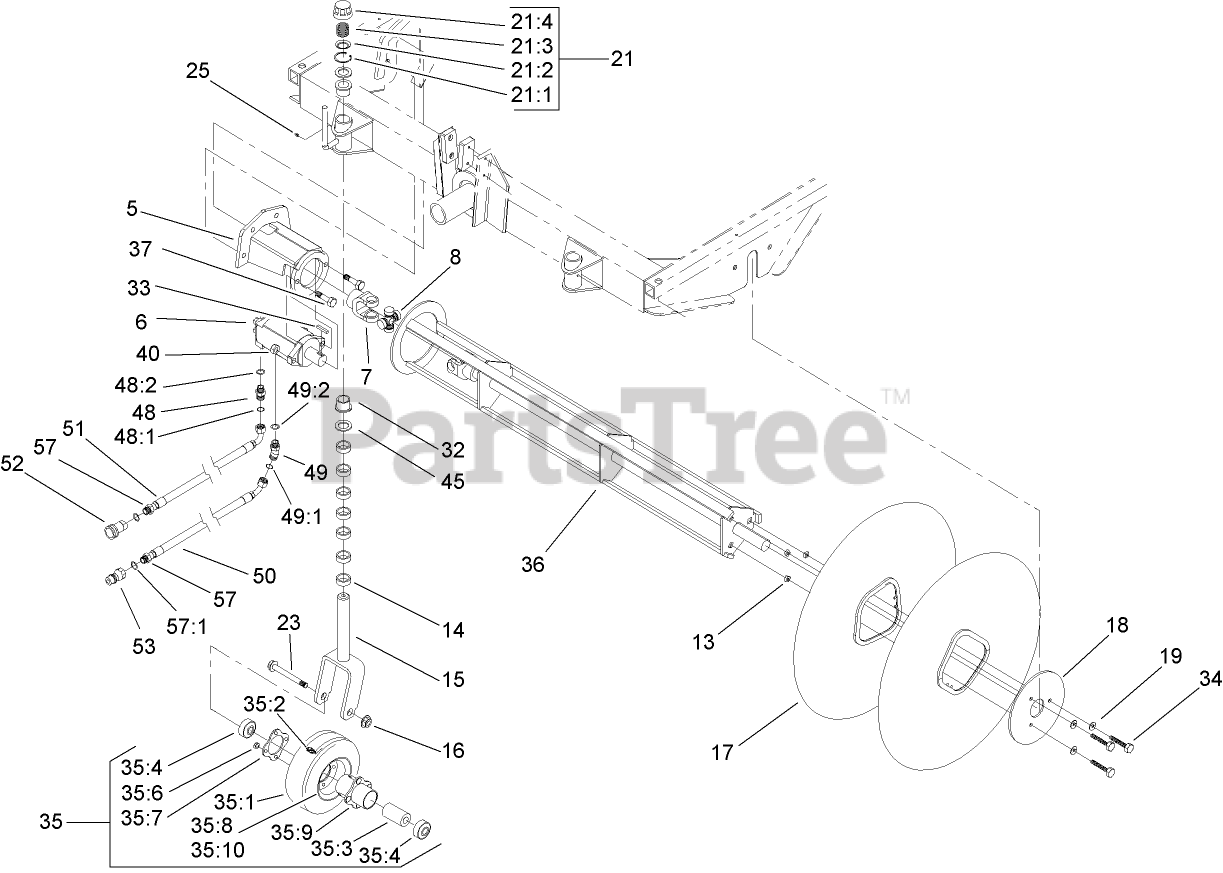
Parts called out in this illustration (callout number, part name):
5	HYD MOTOR MOUNT ASM
6	MOTOR-HYDRAULIC
7	YOKE-KEYED
8	CROSS-YOKE
13	RETAINER-NUT
14	SPACER
15	CASTOR FORK ASM
16	NUT-LOCK, NI
17	ELEMENT-BRUSH, WIRE (OPTIONAL)
17	ELEMENT-BRUSH, POLY
18	PLATE-RETAINER, BRUSH
19	WASHER-LOCK
21	HOC CAP ASM
21:1	RING-RETAINING
21:2	WASHER-CAP
21:3	SPRING-COMPRESSION
21:4	CAP-HOC
23	SCREW-HH
25	FITTING-GREASE
32	BUSHING
33	KEY-STEP
34	SCREW-HH
35	WHEEL ASM
35:2	TUBE-INNER (W/VALVE)
35:3	SPACER-BEARING, INNER
35:4	BEARING
35:6	NUT-HHF
35:7	PLATE
35:8	RIM-WHEEL, HALF
35:10	RIM-WHEEL, HALF
36	ROTOR FRAME ASM
37	SCREW-HH
40	SCREW-HH
45	WASHER
48	FITTING-STRAIGHT
48:1	O-RING
48:2	O-RING
49	FITTING-HYD-45
49:1	O-RING
49:2	O-RING
50	HOSE ASM
51	HOSE ASM
52	COUPLER-FACE, FLUSH
53	NIPPLE-CONNECT, PRESSURE
57	ADAPTER-HYD
57:1	O-RING
